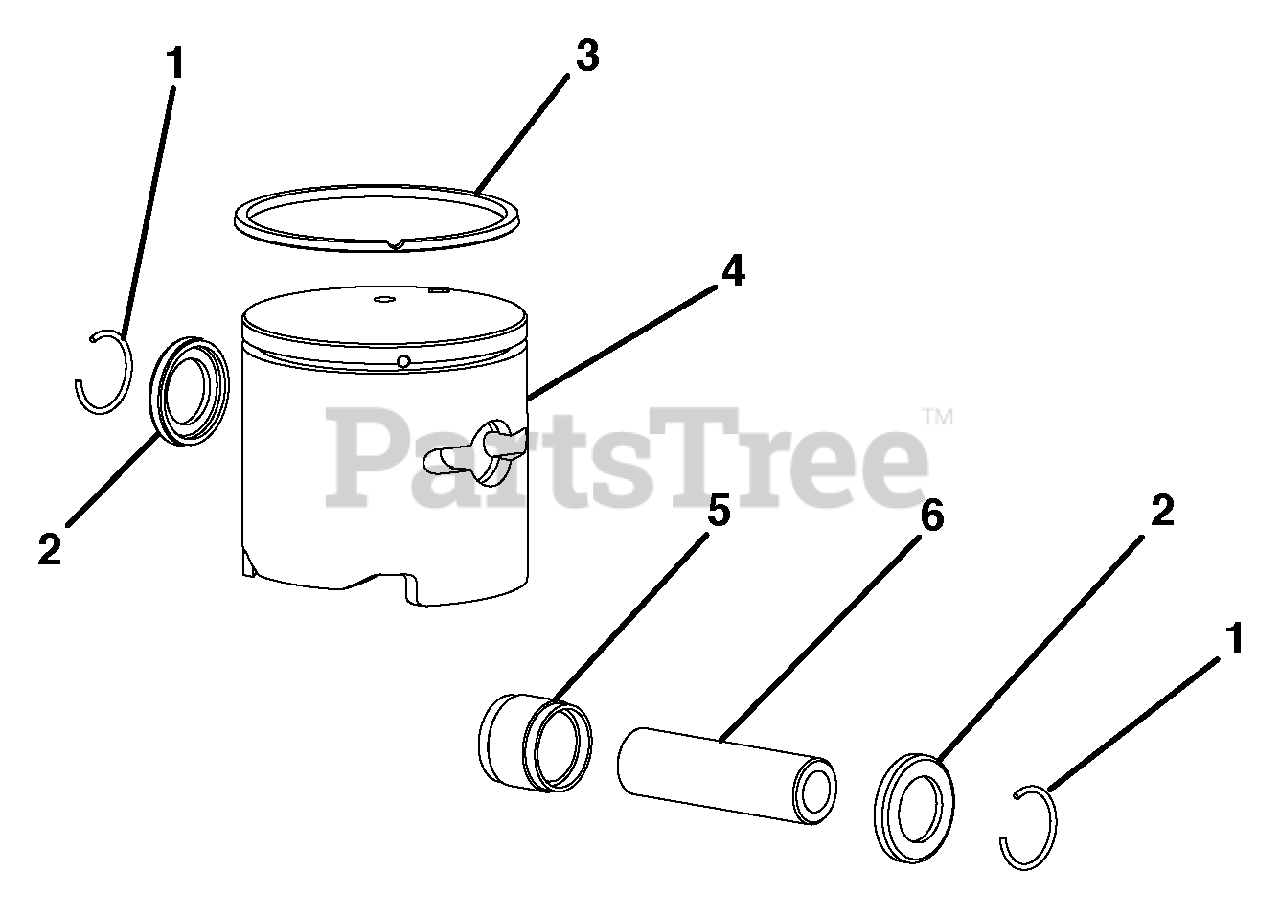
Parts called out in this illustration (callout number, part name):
1	WRIST PIN CLIP RING
2	WASHER
3	PISTON RING
5	NEEDLE BEARING (ID 8 X 8.8)
6	WRIST PIN
